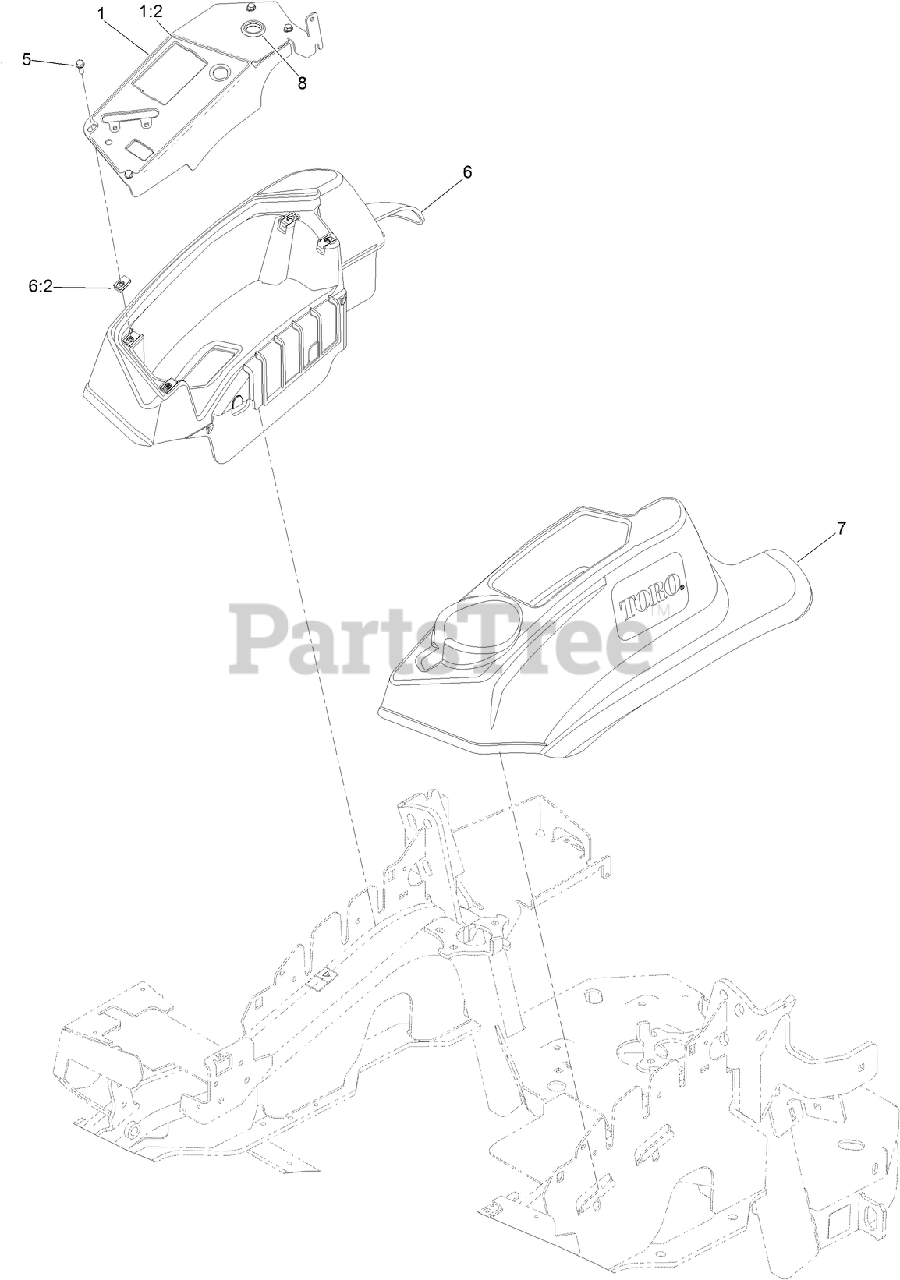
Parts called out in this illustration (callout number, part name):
1	CONTROL PANEL ASM
5	SCREW-HWH
6	RH CONSOLE ASM
7	CONSOLE-LH
8	PLUG-PLASTIC
